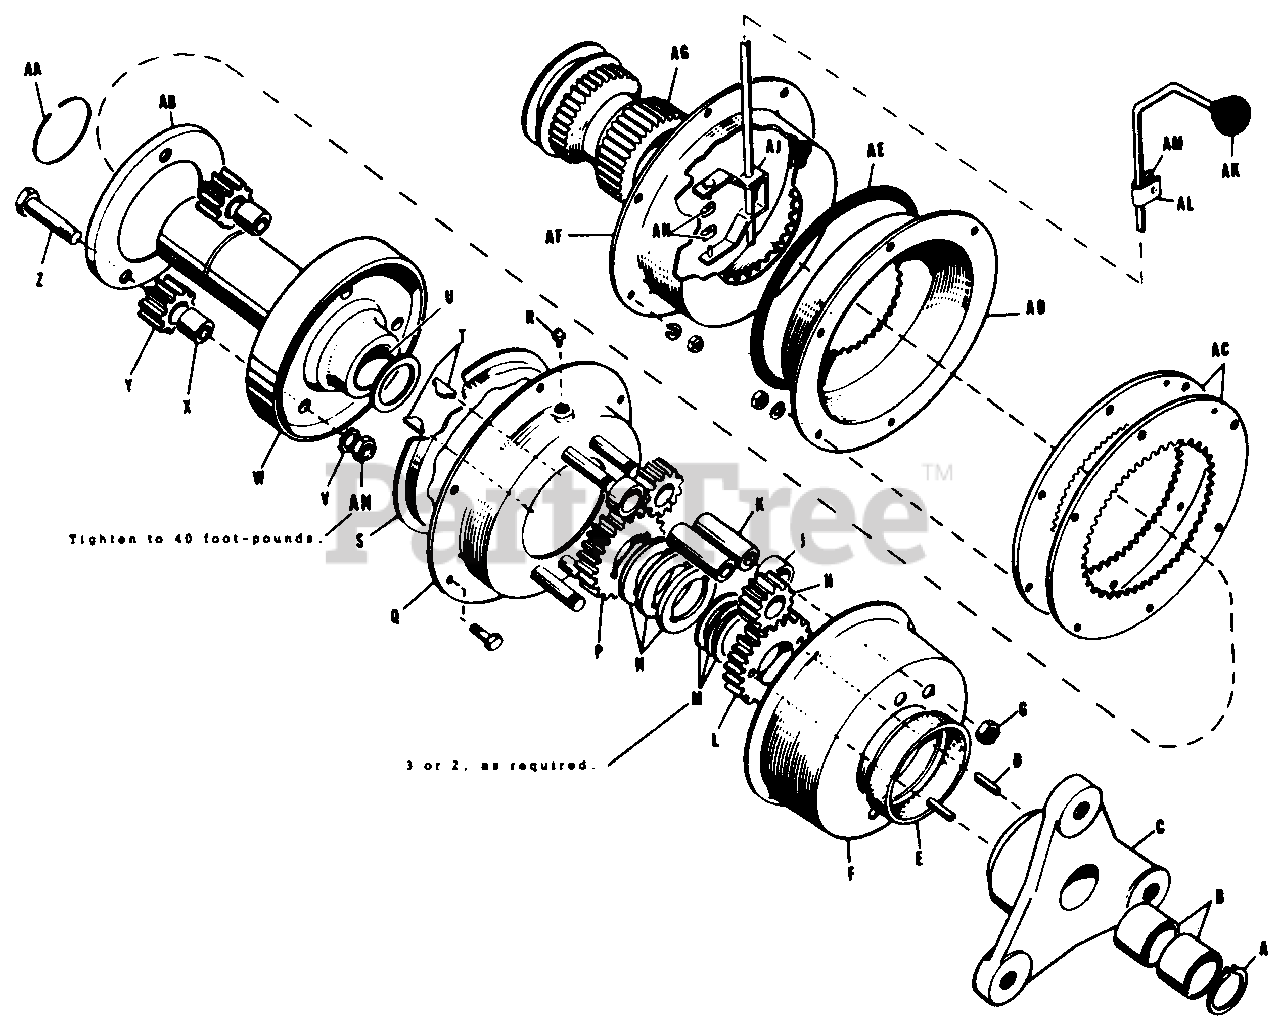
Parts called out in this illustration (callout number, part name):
A	Ring, Retaining
C	Hub, Wheel, R.H.
D	Pin, Roll
E	Seal, Differential Cover
F	Cover, Differential
G	Nut, Lock, Hex Full 3/8-24
H	Pinion, Differential
J	Spacer, Differential
K	Spindle, Pinion, Differential
L	Gear Differential
N	Washer, Axle
P	Gear, Differential
Q	Carrier Assembly
R	Fitting, Grease, Alemite #1641
S	Plate, Thrust
T	Key, Hi-Pro HP608
V	Washer, Lock, External Shakeproof
W	Spider Assembly
X	Spacer, Pinion
Z	Bolt, Hex Hd.
AA	Ring, Snap
AB	Ring, Bolt
AC	Gear, Ring
AD	Cover Assembly
AE	Seal, Housing Assembly
AF	Housing Assembly
AG	Sun Gear Assembly
AH	Block, Shift
AJ	Clevis Assembly
AL	Guide, Rod
AN	Nut, Full Hex
